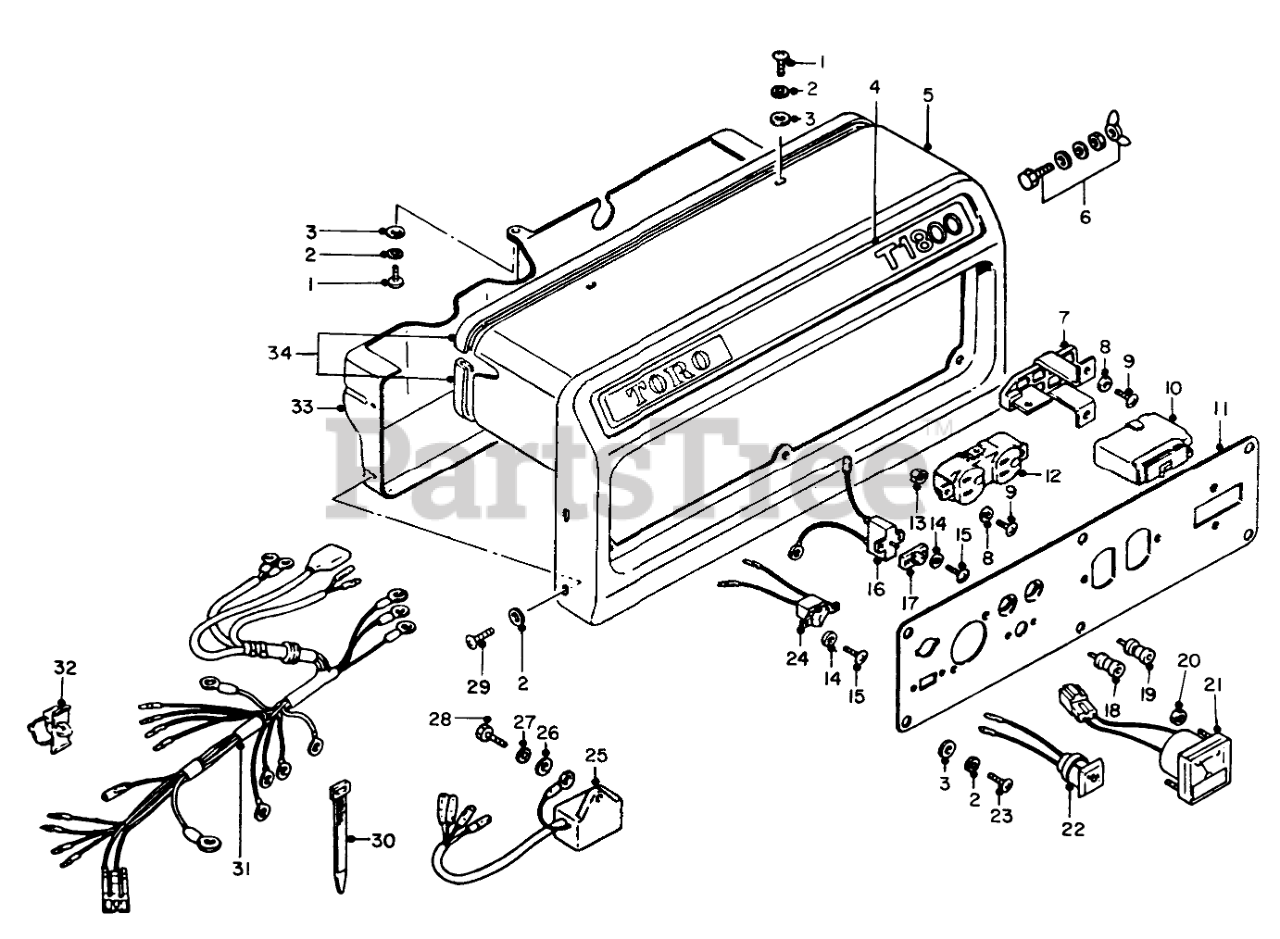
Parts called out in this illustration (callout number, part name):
1	SCREW
2	Washer
3	WASHER
4	Emblem-Toro T1800
5	Panel-Control
6	GROUND TERMINAL
7	BREAKER HOLDER
8	Washer
9	Screw
10	Circuit Breaker
11	PLATE
12	RECEPTACLE
14	Washer
15	Screw
16	Circuit Breaker DC
18	TERMINAL-
21	Meter-Voltage
23	Screw
24	Switch
25	OIL LEVEL UNIT
26	Washer
27	LOCKWASHER
29	Screw
30	Clamp
31	CONTROL HARNESS
32	Clamp
